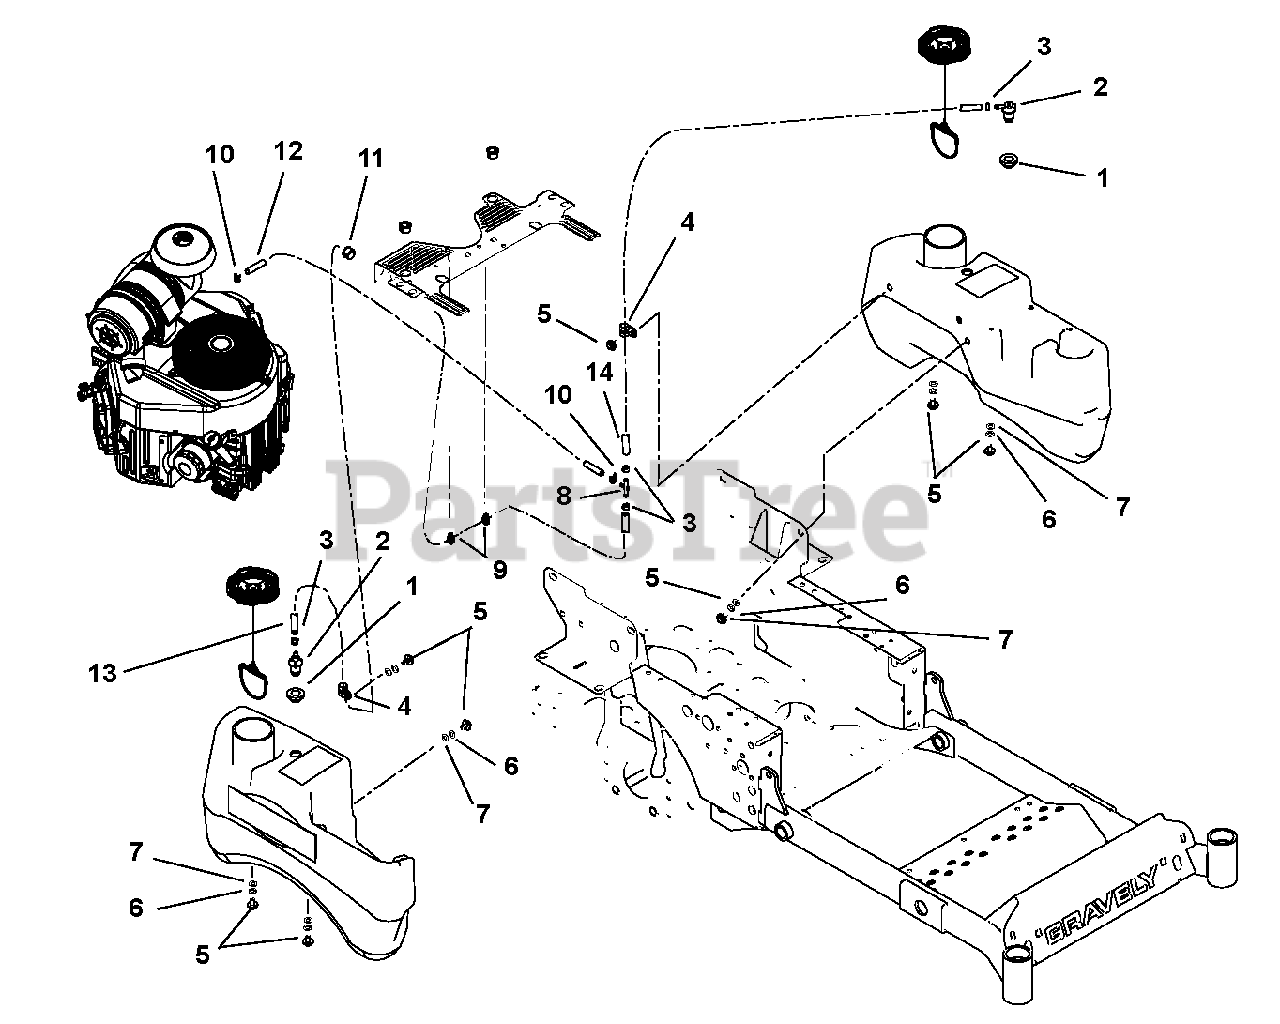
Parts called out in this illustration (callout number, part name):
2	Valve
3	Hose, Clamp
5	Bolt, .31-18 x .62
6	Washer, Locking .31 x .078 Regular
7	Washer, Flat Steel .38 x .875 x .083
8	Fitting, Tee 1/4 x 3/8
9	Clip, Routing
10	Clamp, Spring .188
11	Bushing, Snap
12	Hose, Fuel
13	Hose, Fuel
14	Hose, Fuel
